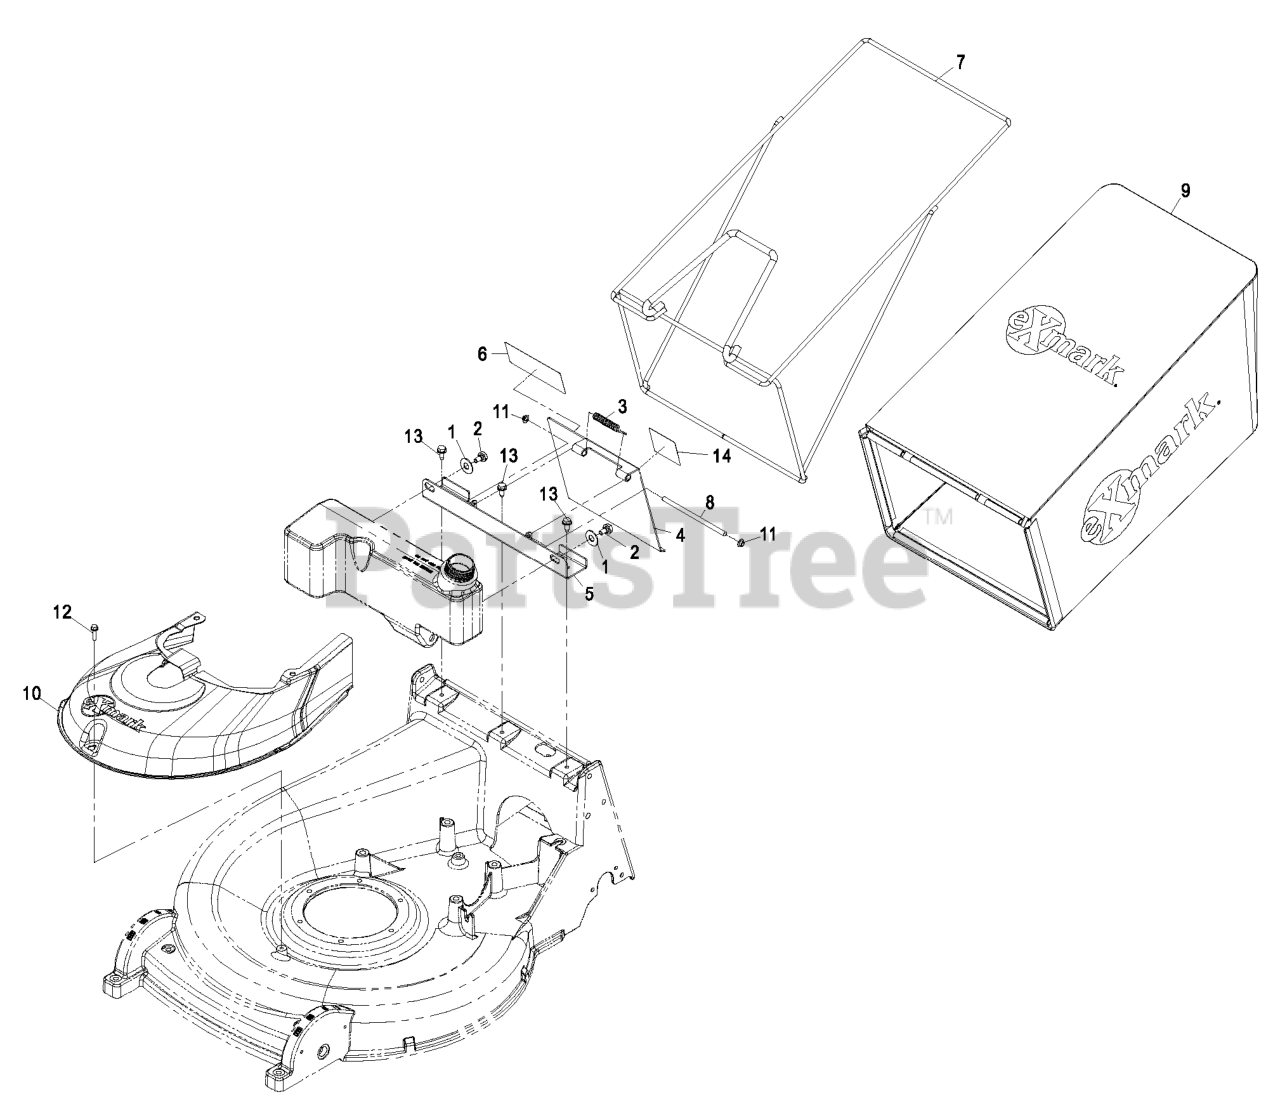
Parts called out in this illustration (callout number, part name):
1	WASHER-PLASTIC
2	BOLT-SHOULDER,HFH
3	SPRING-TORSION
4	ASM,DOOR W/DECALS METRO 2
5	BRACKET-MOUNT, BAG/DOOR
6	DECAL-WARNING
7	FRAME-BAG
8	ROD-PIVOT, DOOR
9	BAG,METRO 26 3.0 BU
10	COVER,SPINDLE
11	NUT-PUSH
12	SCREW-HWHTF
13	Screw-HWH 5/16-18 X 3/4 Tf
14	DECAL,SERVICE M26
